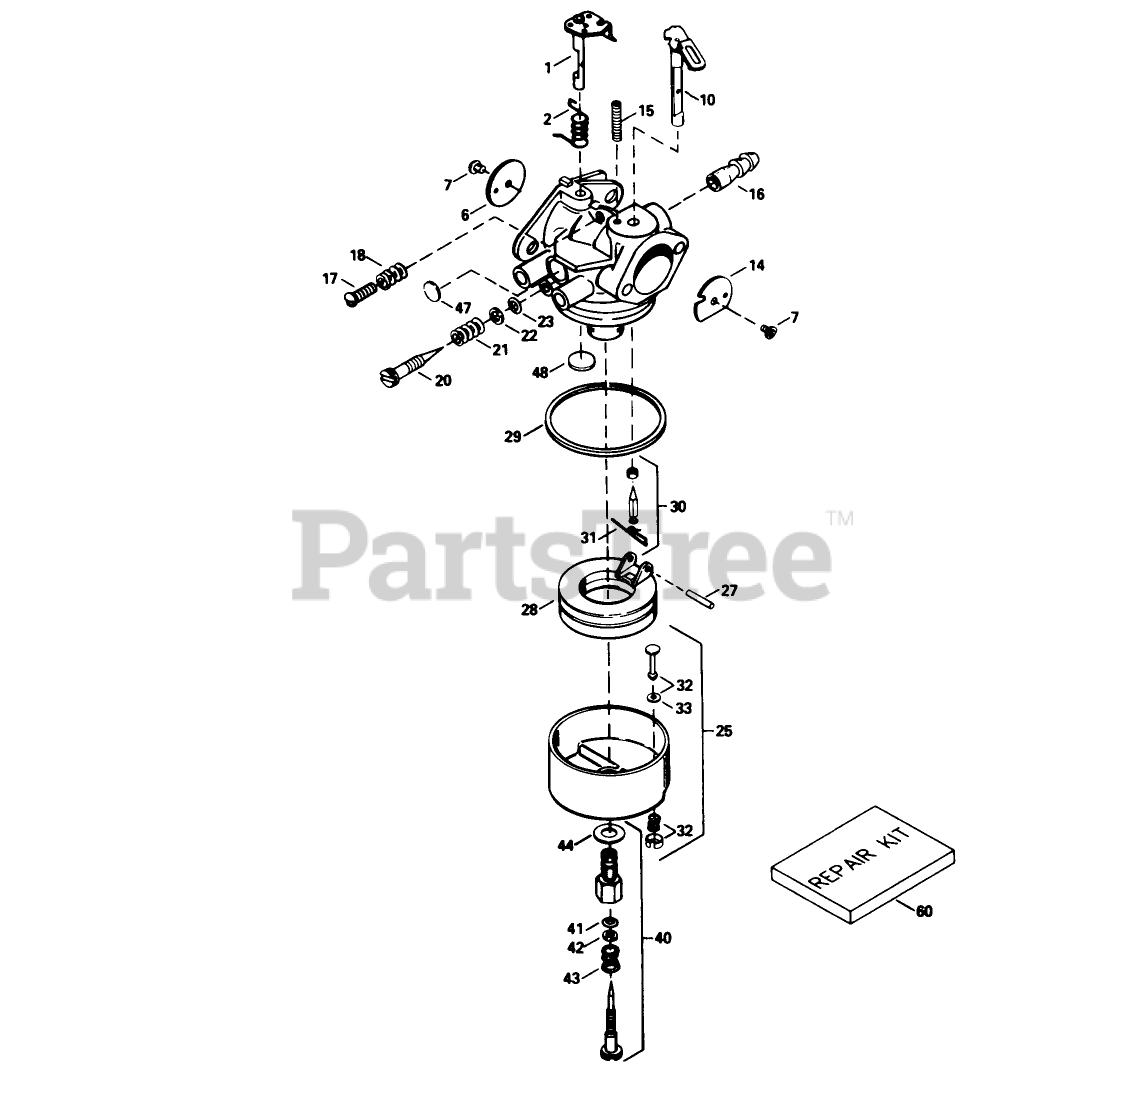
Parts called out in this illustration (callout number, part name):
1	Throttle Shaft and Lever ASM
2	Spring-Return, Throttle
6	Shutter-Throttle
7	Screw-Shutter
10	Choke Shaft and Lever ASM
14	Shutter-Choke
15	Spring-Positioning, Choke
16	Fitting-Fuel
17	Screw-Throttle Crack Screw / Idle Speed
18	Spring-Tension
20	Screw-Idle Mix
21	Spring-Tension
22	Washer
23	ORing
25	Float Bowl Asm. (Incl. Ref. # 32, 33)
27	Shaft-Float
28	Float
29	O Ring-Bowl, Float
30	Inlet Needle, Seat Clip Assy. (Incl. No. 13)
31	Clip-Spring
32	Bowl Drain ASM
33	Gasket-Plunger, Drain
40	Adjustment Screw Assy.,Main (Incl. Ref. #5A,21,23 30)
41	ORing
42	Washer
43	Spring
44	Washer-Bowl Nut
47	Plug-Welch, Idle Mixture Well
48	Plug-Welch, Atmospheric Vent
60	Kit-Repair
